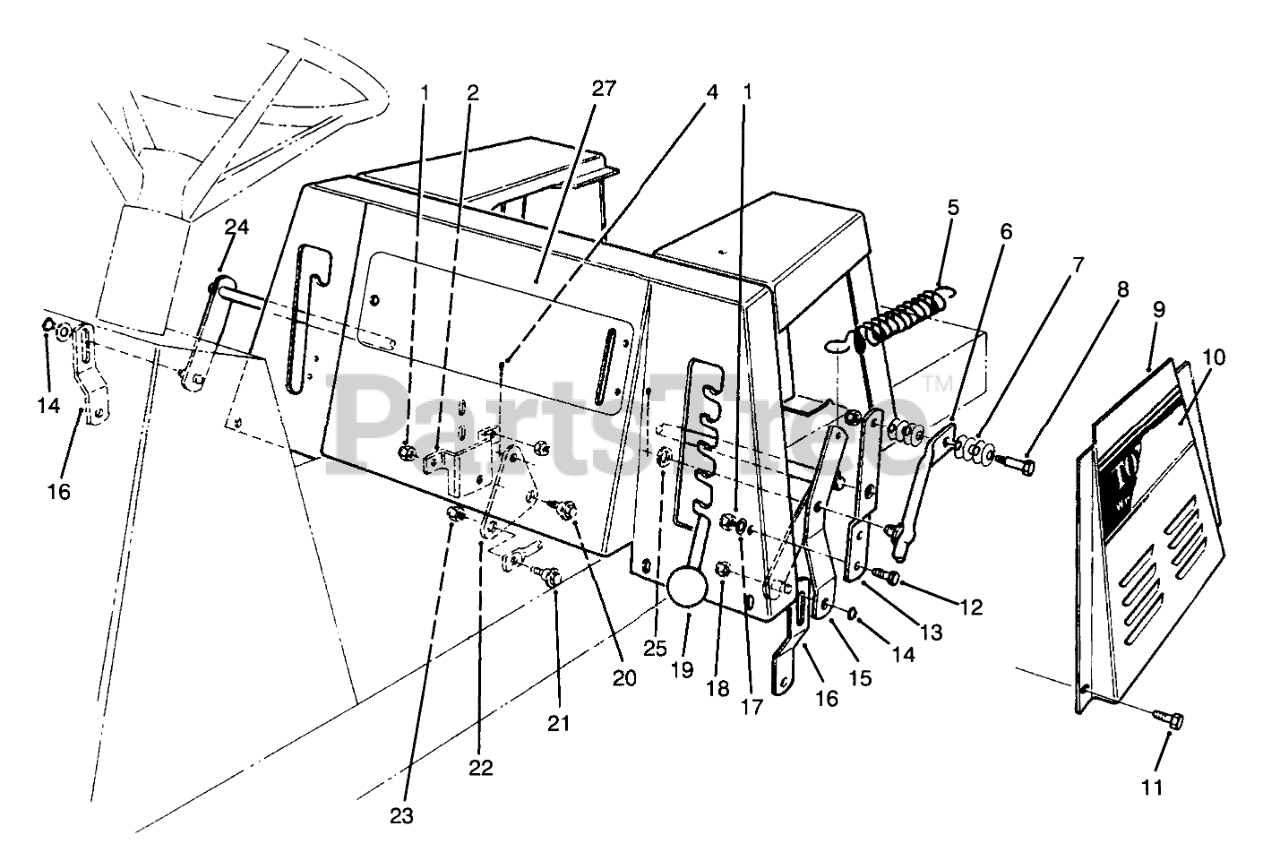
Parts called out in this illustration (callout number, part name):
1	NUT-LOCK, NI
2	BRKT-B.CRANK MTG
4	PIN-COTTER
5	SPRING-EXTENSION
6	HOC LEVER WA B
7	WASHER-BELLEVILLE
8	BOLT-SHOULDER
9	Panel L.H.-Base, Seat
10	DECAL - TORO 1132 LH
11	SCREW-HH
12	SCREW-HH
13	Bracket
14	RING-RETAINING
15	Bracket-H.O.C., Engage
16	Link-Deck Suspension
17	WASHER-PLAIN
18	NUT-LOCK, NI
20	SCREW-SHOULDER
21	SCREW-SHOULDER
22	BELLCRANK
23	NUT-HEX
24	Arm
25	WASHER-FLAT
27	DECAL - CONTROL PANEL
